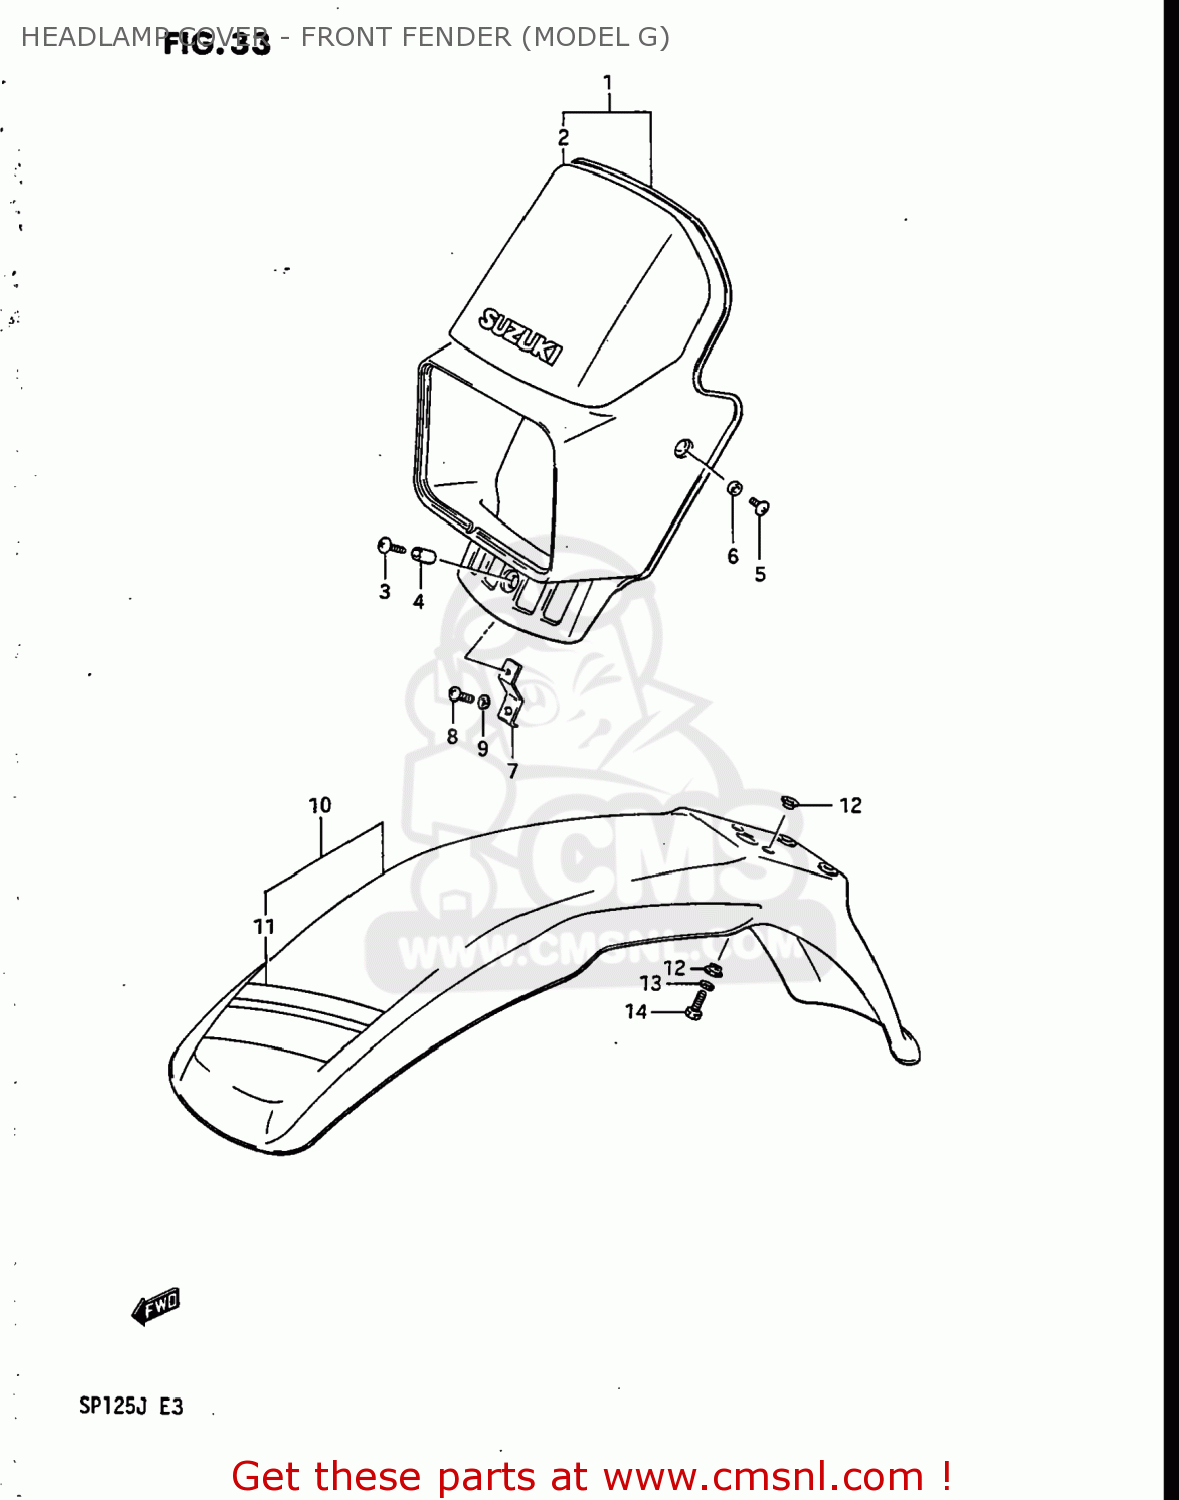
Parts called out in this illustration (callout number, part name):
1	COVER,HEADLAMP
2	TAPE SET,HEADLAMP COVER
3	SCREW, CENTER
4	SPACER (6.1X8X12)
5	SCREW 6X12
6	SPACER (6.1X8X3.5)
7	BRACE,HEADLAMP HOUSING LWR
8	SCREW 6X12
9	WASHER,LOCK
10	FENDER,FRONT
11	TAPE SET,FRONT FENDER
12	SPACER
13	WASHER,LOCK
14	BOLT, UPPER
